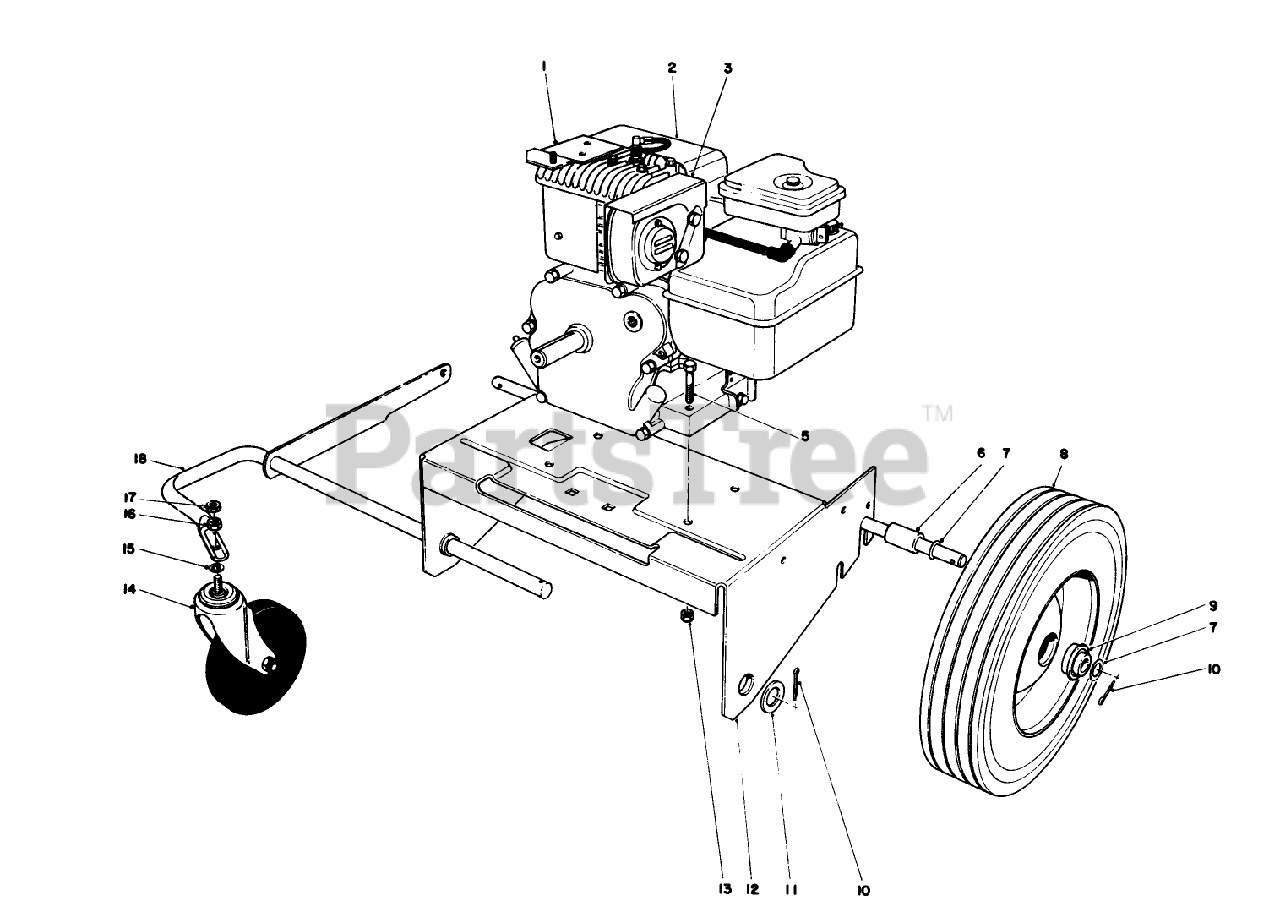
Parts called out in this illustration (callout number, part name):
1	MTG BRKT WA *B
2	ORDER FROM BRIGGS
3	HEAT SHIELD
5	SCREW-HH
6	SPACER-AXLE
7	WASHER
8	WHEEL
9	BEARING
10	PIN-COTTER
11	WASHER-FLAT
13	NUT-LOCK, CONE
14	CASTER
15	Lockwasher
16	NUT-HH
